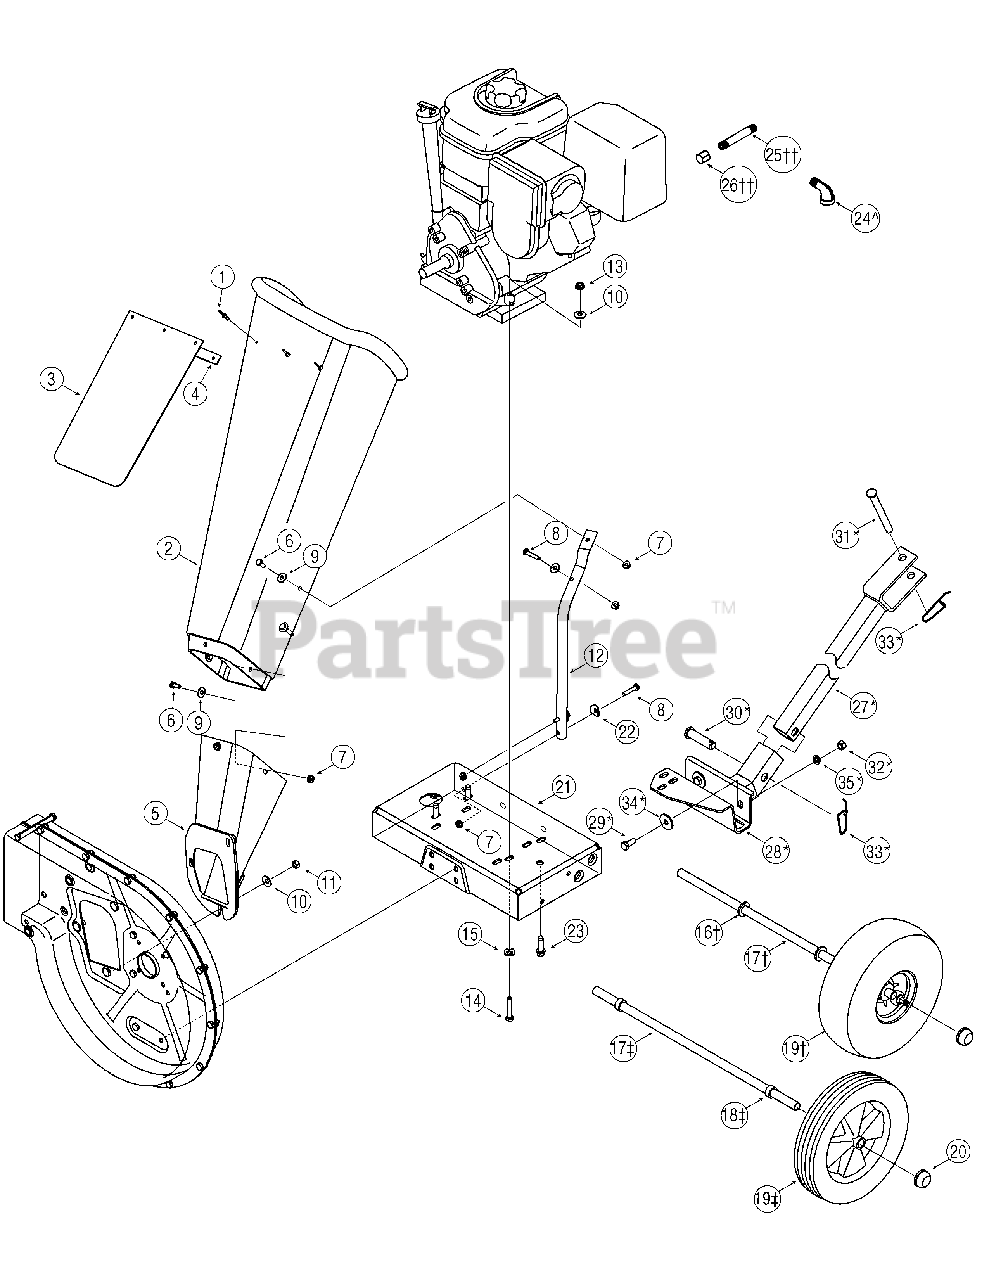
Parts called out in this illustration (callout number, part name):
1	Pop Rivet
2	Chipper Shredder Chute
3	Chute Flap
4	Chute Flap Strip
7	Hex Lock Nut 1/4-20
8	Hex Cap Screw 1/4-20 x 1.25
9	Flat Washer.28 ID x.74 OD
10	Bell Washer.340 ID x.872
11	Hex Nut 5/16-18
13	Hex Lock Nut 5/16-18
14	Hex Cap Screw 5/16-18 x 1.5
14	Hex Cap Screw 5/16-18 x 1.75 - Model Series 464G Only
15	Bell Washer 5/16 x 1.0
16	Flat Washer Model Series 464
17	Axle Assembly Model Series 462
17	Axle Assembly Model Series 464
18	Spacer Model Series 462
19	Wheel Comp., 10.0 x 2.5 Plastic, Model Series 462
19	Wheel Complete, 10.0 x 4. Gray Model Series 464
20	Push Cap
22	Washer,.320 ID x.93 OD
23	Screw, 3/8-16 x 1.250
24	Elbow Fitting, Models 462 & 464D
25	Oil Drain Pipe - Model Series 464G Only
26	Oil Drain End Cap - Model Series 464G Only
29	Hex Cap Screw, 3/8-16 x .88 (if equipped)
30	Clevis Pin,.625 x 2.4 (if equipped)
31	Clevis Pin,.50 x 4.62 (if equipped)
32	Hex Nut, 3/8-16 (if equipped)
33	Spring Pin (if equipped)
34	Flat Washer,.411 x 1.25 x 1.0 (if equipped)
35	Lock Washer, 3/8 (if equipped)
